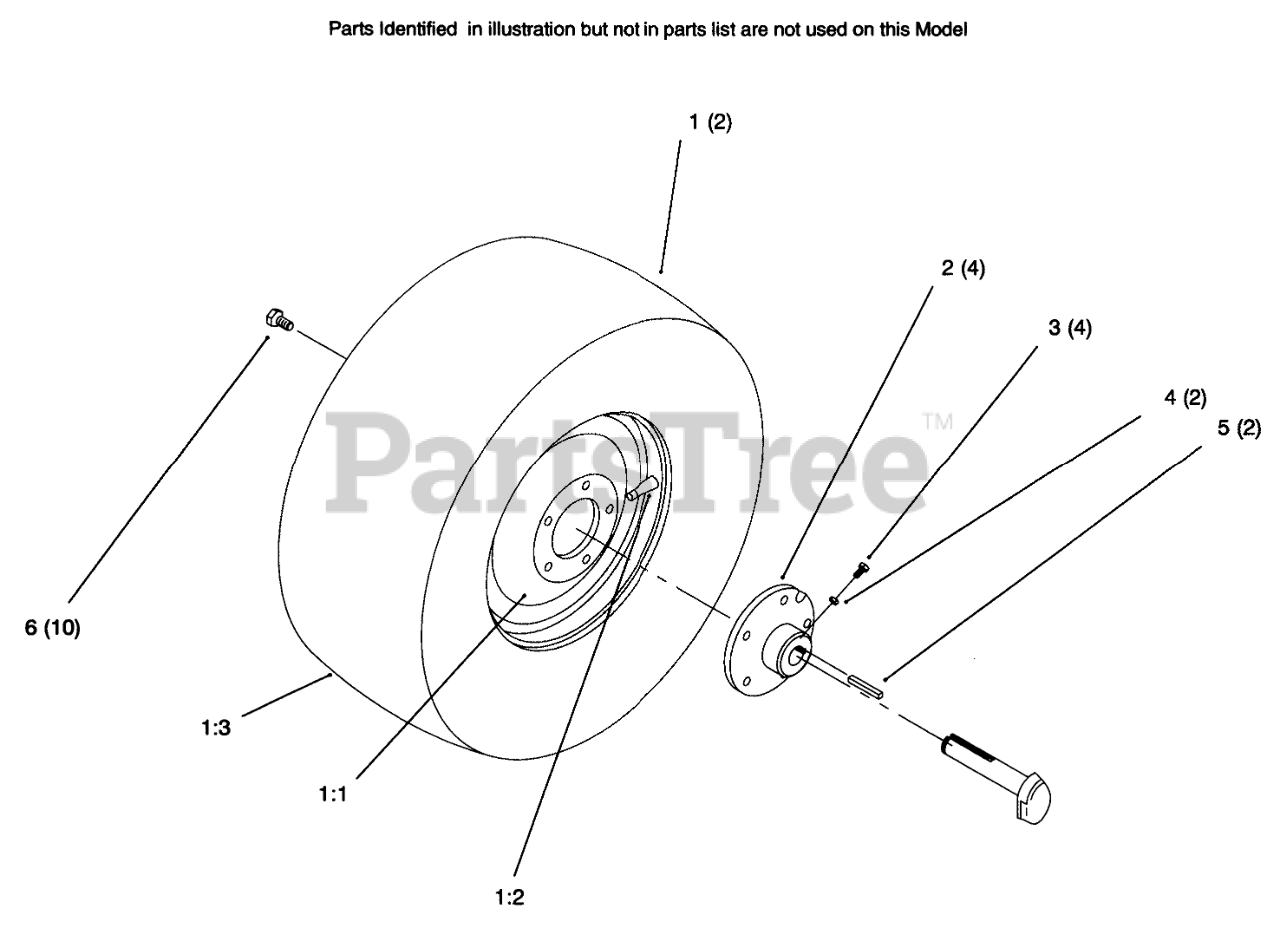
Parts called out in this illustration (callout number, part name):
1	Wheel AND Tire ASM
1:1	WHEEL
1:2	VALVE
1:3	TIRE
2	HUB-WHEEL
3	SCREW-SET, SQH
4	NUT-JAM
5	KEY-SQUARE
6	BOLT-LUG
